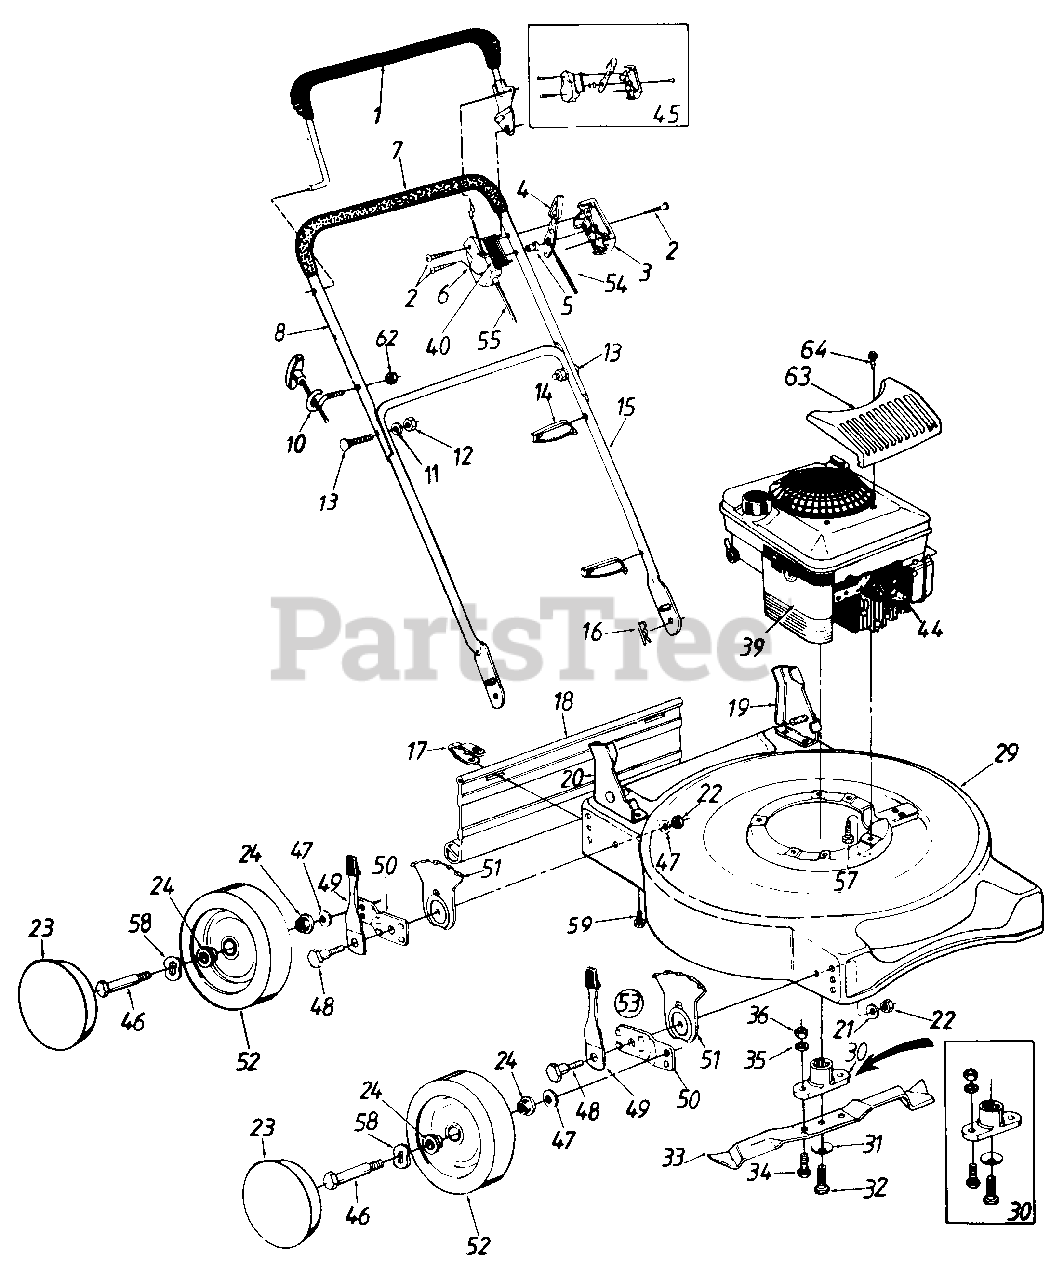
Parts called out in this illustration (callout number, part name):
1	Control Handle Ass'y.
2	Truss Mach. Scr. #12 x 1.5" Lg.
3	Control Panel Half
4	Throttle Control Lever
5	Control Disc Pin
6	Clutch Panel Half
7	Grip
8	Upper Handle
10	Rope Guide
11	L-Wash. 5/16" I.D.
12	Hex Nut 5/16-18 Thd.
13	Curved Carriage Bolt 5/16-18 x 1.38" Lg.
14	Cable Tie
15	Lower Handle
16	Hairpin Cotter
17	Hinge Clip
18	Rear Flap
19	Handle Bracket Ass'y. L.H.
20	Handle Bracket Ass'y. R.H.
21	Bell-Wash. .39" I.D. x 1.38"
22	Hex Nut 3/8-16 Thd.
23	Hub Cap (Beige)
24	Ball Bearing
29	20" Deck Ass'y.
30	Blade Adapter Kit (Splined)
31	Bell-Wash..46" I.D.
32	Hex Bolt 7/16-20 x 1.5" Lg.
33	20" Mulchina Blade
34	Hex Bolt 3/8-24 x 1" Lg.
35	L-Wash. 3/8" I.D.
36	Hex Nut 3/8-24 Thd.
39	Engine
40	Throttle Label
44	Spark Plug Boot
45	Kit Control Housing Comp.
46	Axle Bolt
47	Bell-Wash. .400" I.D. x .88"
48	Shld. Bolt .50" Dia. x .357"
49	Spring Lever Ass'y. w/ Knob
51	Height Adj. Plate
52	Wheel Ass'y. Comp. (Beige)
53	Height Adj. Ass'y. Comp. R.F. & L.R.
54	Throttle Cable 51"
55	Control Cable 35"
57	Hex L-Wash. Hd. Scr. 3/8-16 x 1.0" Lg.
58	Wave Washer .53" I.D.
59	Hex Wash. Hd. B-Tap Scr. 5/16-18 x .5" Lg.
62	Hex L-Nut 1/4-20 Thd.
63	Engine Cover
64	Truss Hd. Tap Scr. #6 x .6" Lg.
